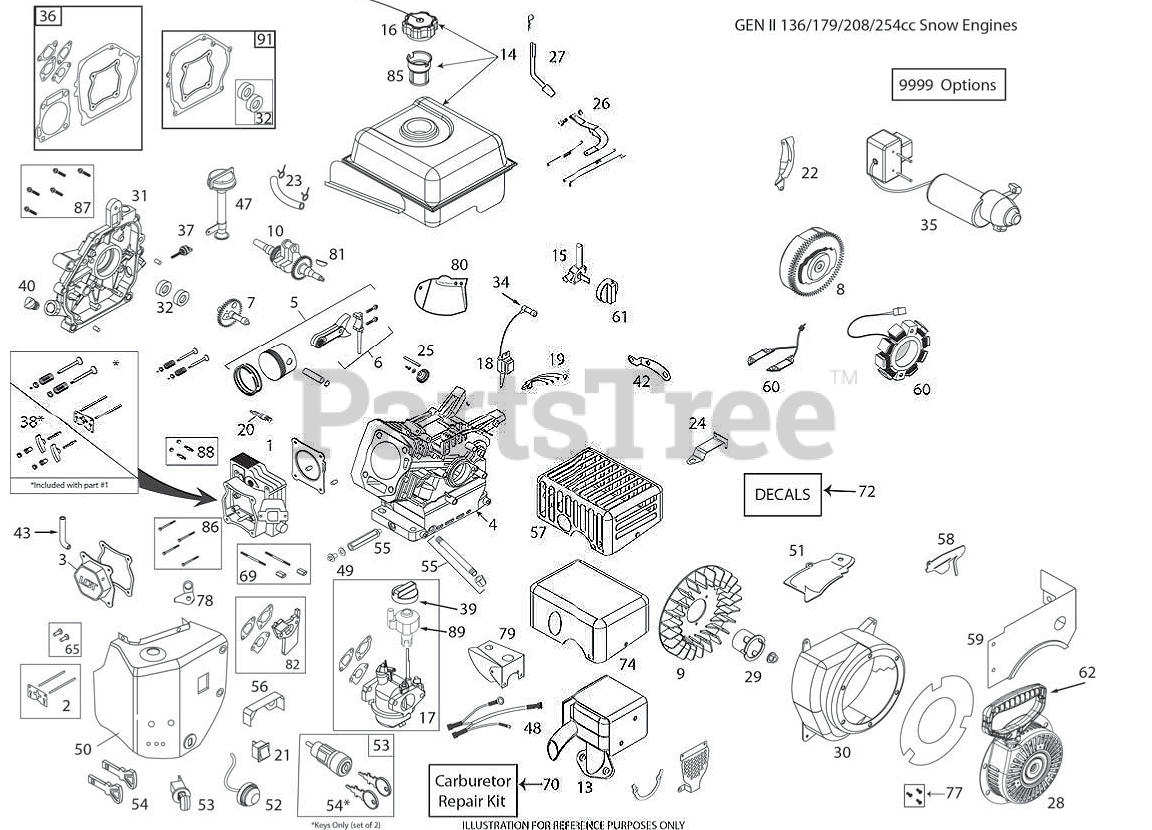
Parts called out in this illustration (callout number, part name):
1	CYLINDER.HEAD.ASM.W/GASKET.254
2	KIT.PUSH.ROD.&.PLATE.W/VC.GASK
3	COVER.VALVE.W/GASKET.254CC
5	PISTON.&.ROD ASSEM.254CC
7	CAMSHAFT.MCR.W/GASKET.254CC
8	FLYWHEEL.ELEC.STRT.(8.MAGNETS)
9	FLYWHEEL FAN 420586
10	CRANKSHAFT.KEYED(#18).SNOW.254
13	MUFFLER.ASSEM.GEN2.SNOW.254CC
14	FUEL.TANK.SNOW.2.7L.BLACK.254C
15	FUEL.PETCOCK.SNOW(SKSN4900)
16	FUEL CAP OVERSIZED CLICK STYLE
17	CARBURETTOR LCT 254 W/IDLEDOWN
18	COIL.ING.CDI.HI TEMP.SKSNO416.
20	PLUG.SPARK.PLAT.SKSN2404.1
21	SWITCH.ON/OFF(SKSN-0403)
22	SHIELD.FLYWHEEL.ELEC.STRT.208C
23	KIT.FUEL.HOSE.208CC.SING/STAGE
24	BRACKET.SPEED.CNTRL.FIXED.254C
25	GOVENOR.GEARS ASM(SK2082900)
26	KIT.GOVERNOR.ARM.&.LINK.254CC
27	KIT.GOVERNOR.CRANK(SK208-3100)
28	RECOIL.STRT.ROUND(BLK) SNOW
29	STRTER.CUP(NON-SLOT)SKSN0601.2
30	BLOWER HSG.LCT 254 GLOSS BLK S
31	CRANKCASE.CVR.PRESS.IN.HI-OIL.
32	KIT.SEAL.OIL.2.PIECES.254CC
34	SPARK.PLUG.BOOT.SNW,SKSN4691.1
35	STARTER.EL.230C.SNO.LCT.208CC.
35	ELEC.START.GEN2.SKSN0451.1
36	KIT.ENGINE.GASKET.254CC
38	KIT.ROCKER.ARM.W/GASKET.254CC
39	CHOKE.KNOW.SNOW(SKSN4500)
40	NON REMOVABLE PLUG
43	TUBE.BREATHER.LCT.208
47	TUBE ASSY HIGH OIL-FILL
48	WIRE.HARNESS.SNOW
49	KIT.OIL.DRAIN.PLUG(SK2089911
50	KIT.HEATER.BOX.SNOW.254CC
52	PRIMER.BULB.WITH HOSE (SNOW)
53	SWITH.KEY.ASSEM.SNOW.SINGLE.ST
54	KEY SET(2 KEYS) SKSN0407.1
55	OIL PIPE DRAIN LCT 254
56	SHIELD.CARBURETOR.VAPOR
58	SHIELD.GOVERNOR.LINKAGE.254CC
59	FUEL TANK SKIRT SHIELD LCT 254
60	208CC 60W ALTERNATOR
61	FUEL KNOB-SNOW
62	HANDLE.RECOIL.DELUXE.LCT
65	TAPPET.KIT.LCT.208CC
69	CARB.STUDS & COUPLING KIT.SNOW
70	CARB.REPAIR.KIT.LCT.SK9900.2
74	COVER.MUFFLER.HEAT.SHIELD.
77	BOLT.KIT.RECOIL.LCT.ALL.ENGINE
79	COVER.CARBURETOR.SNOW
80	SHIELD.GOVERNOR.LINK.SNOW.254C
81	KEYS.FLYWHEEL.136/291CC.5PACK
82	SPACER.CARBURETOR.208CC.LCT
85	STRAINER.FUEL.TANK.LCT.208CC
86	KIT.BOLT.CYLINDER.HEAD.(4PC)
87	KIT.BOLT.CRANKCASE.COVER.6PC
88	STUD.MUFFLER.KIT.LCT
89	KNOB LCT.SKSN5325.1 SPEED
91	CRANKSHAFT GASKET KIT.LCT
9999	KIT.BOLT.LCT.SK9990.1
9999	JET HIGH ALTITUDE LCT 5000 25
9999	STARTER SCREW.STARTER SWITCH B
